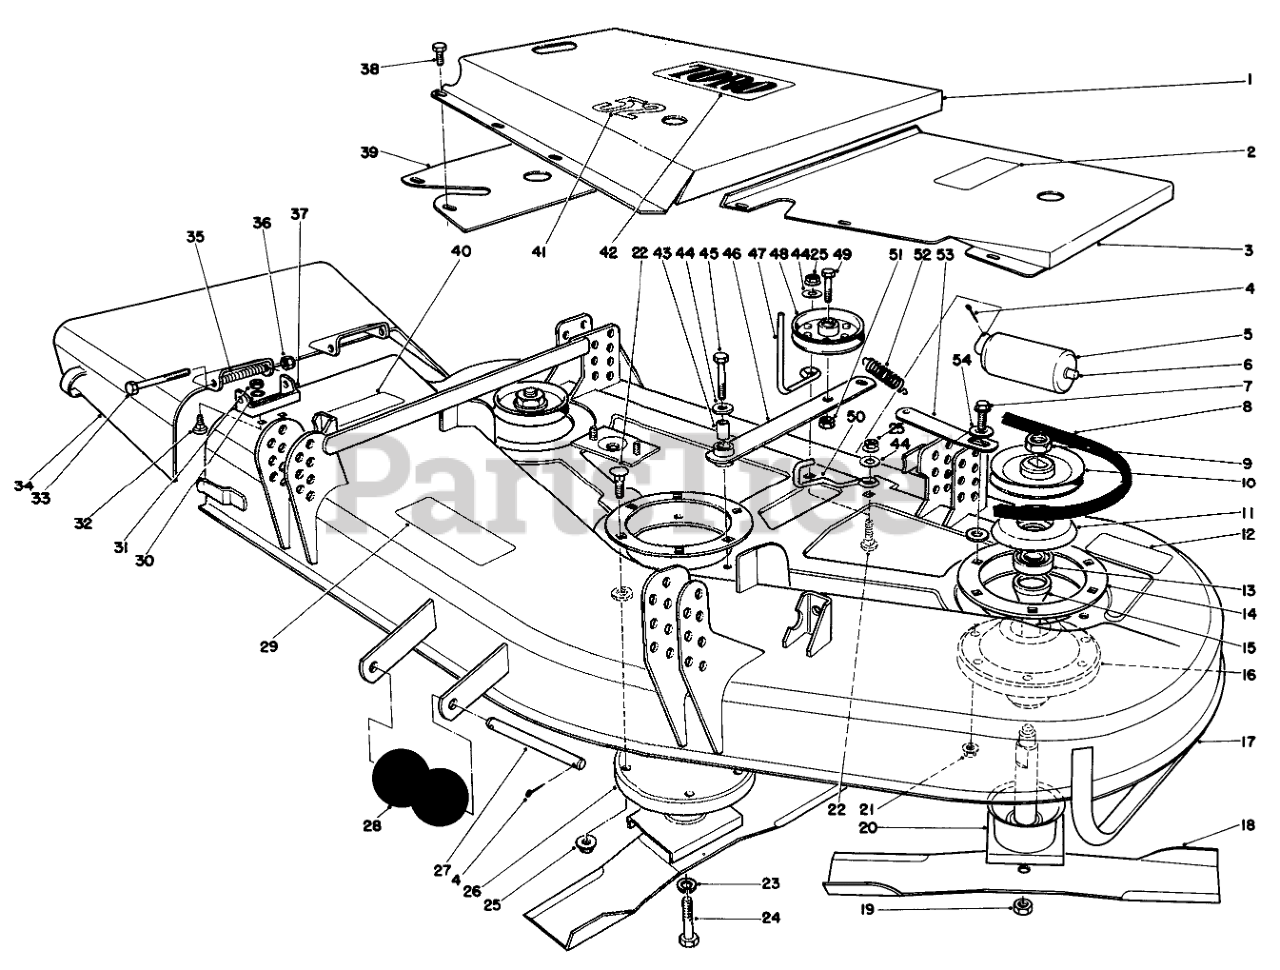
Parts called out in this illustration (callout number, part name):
1	CENTER COVER WA 52 R
2	DECAL
3	Cover
4	PIN-COTTER
5	ROLLER-DECK
6	SHAFT-ROLLER, REAR
7	SCREW-HHF
8	V-BELT
9	Locknut
10	PULLEY and HUB ASM
11	COVER-DUST
12	DECAL-CAUTION, BLADE
13	BEARING
14	SUPPORT-DECK, RING
15	SPACER-GREASE SHIELD
16	Spindle ASM
17	Deck Assembly
18	Blade
19	Locknut
20	SHAFT and SADDLE ASM
21	NUT-LOCK, FLANGE
22	SCREW-CARR
23	WASHER-LOCK/SP
24	SCREW-BLADE
25	NUT-HF
26	SPINDLE ASM
27	SHAFT-ROLLER
28	ROLLER
29	Decal-Caution
30	WASHER-LOCK
31	NUT-HEX
32	SCREW-CARR
33	SCREW-HH
34	Deflector
35	SPRING
36	NUT-HEX
37	Bracket-Pivot
38	SCREW-HHFTF
39	Cover
40	DECAL-CAUTION, DEFLECTOR
41	DECAL
42	Decal-Toro
43	SLEEVE
44	WASHER-FLAT
45	SCREW-HH
46	ARM-IDLER, DECK
47	ROD-BELT
48	Pulley
49	SCREW-HH
50	BELT GUIDE
51	NUT-HEX
52	SPRING-EXTENSION
53	Plate-Spring Support
54	WASHER-FLAT
